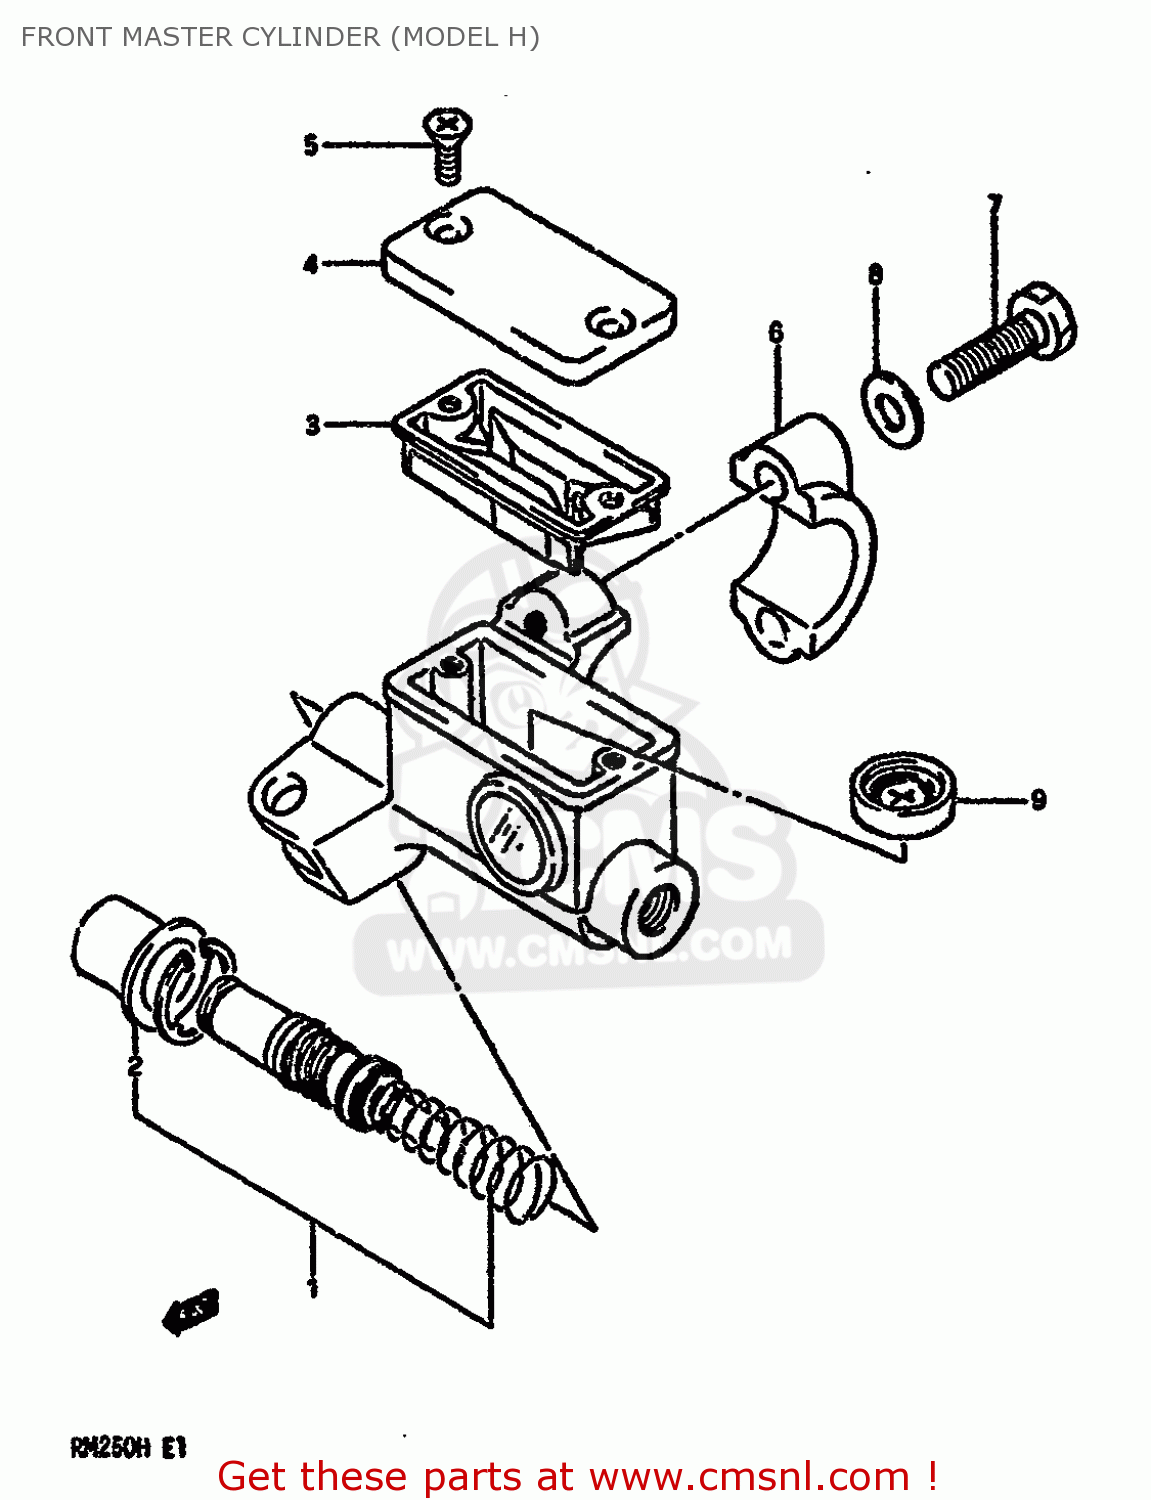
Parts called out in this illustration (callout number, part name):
1	PISTON & CUP SET
2	BOOT
3	DIAPHRAGM
4	CAP
5	SCREW
6	HOLDER,MASTER CYLINDER
7	BOLT
8	WASHER
9	SEPARATOR
